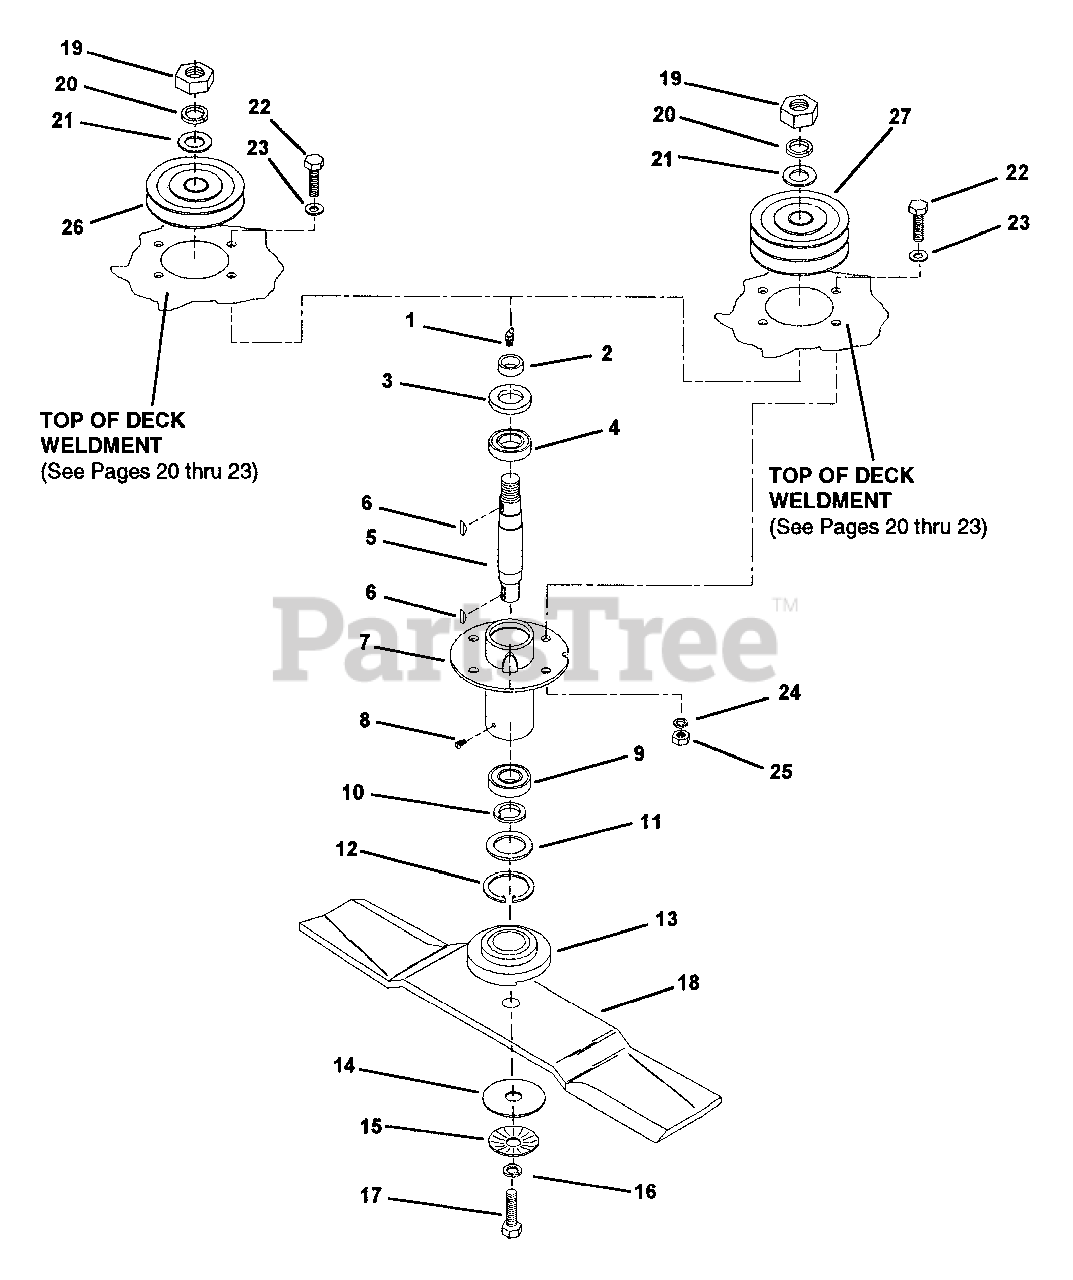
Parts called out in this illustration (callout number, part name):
1	GREASE FITTING
2	SEAL RACE
3	OIL SEAL
4	BALL BEARING: SST # 6205
5	SPINDLE SHAFT
6	WOODRUFF KEY 1/4 X 3/4
7	SPINDLE HOUSING
8	DRIVE, SCREW # 4
9	BALL BEARING: NTN #6205-RS
10	ARBOR SPACER
11	SEAL WASHER
12	SNAP RING: 52 MM INTERNAL BORE
13	BLADE SPACER
14	FLAT WASHER, 1/2 X 2-1/2
15	CUPPED WASHER, 1/2"
16	LOCK WASHER, STANDARD: 1/2"
17	CAP SCREW HX, 1/2-13 X 1-1/2" LG.
18	BLADE: LOW LIFT 17" CUT, 48" DECK
19	NUT, HEX JAM: 3/4
20	LOCK WASHER, SPLIT SPRING: 3/4
21	FLAT WASHER, NARROW: 3/4
22	CAPSCREW, HEX HD: 3/8-24 NF X 1-1/2
23	SPINDLE REINFORCEMENT
24	LOCK WASHER, SPLIT SPRING: 3/8
25	LOCKNUT, M-F:3/8-24 NF
26	PULLEY, 4 DIA. SPLIT STEEL
27	PULLEY, 2 GROOVE, SPLIT STEEL
